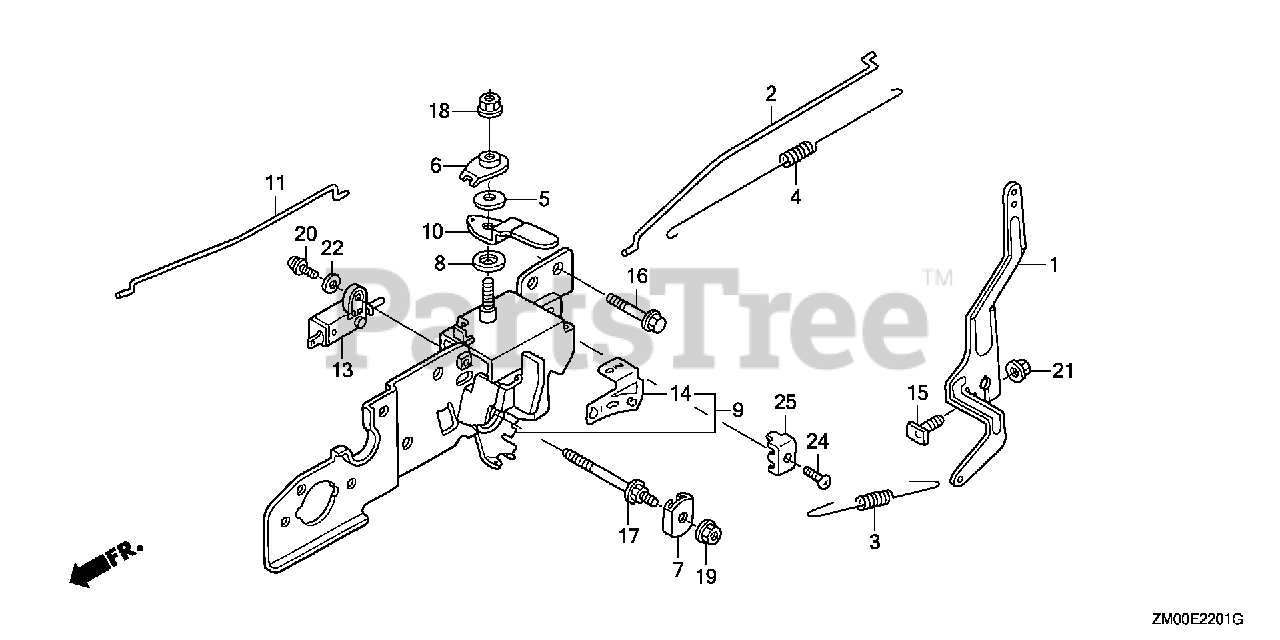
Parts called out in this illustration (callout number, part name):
1	ARM, GOVERNOR
2	ROD, GOVERNOR
3	SPRING, GOVERNOR
4	SPRING, THROTTLE RETURN
5	SPRING, LEVER
6	WASHER, CONTROL LEVER
7	PLATE, LEVER CENTER
8	SPACER, CONTROL LEVER
9	BASE, CONTROL
10	LEVER, CHOKE
11	ROD, CHOKE
13	SWITCH ASSY., ENGINE STOP (N.O)
14	MARK, THROTTLE INDICATION
15	BOLT, GOVERNOR ARM
16	BOLT, FLANGE (6X32)
17	BOLT, SPECIAL (6X45)
18	NUT, SELF-LOCK (6MM)
19	NUT, SELF-LOCK (5MM)
20	SCREW-WASHER (4X12)
21	NUT, FLANGE (6MM)
22	WASHER, PLAIN (4MM)
